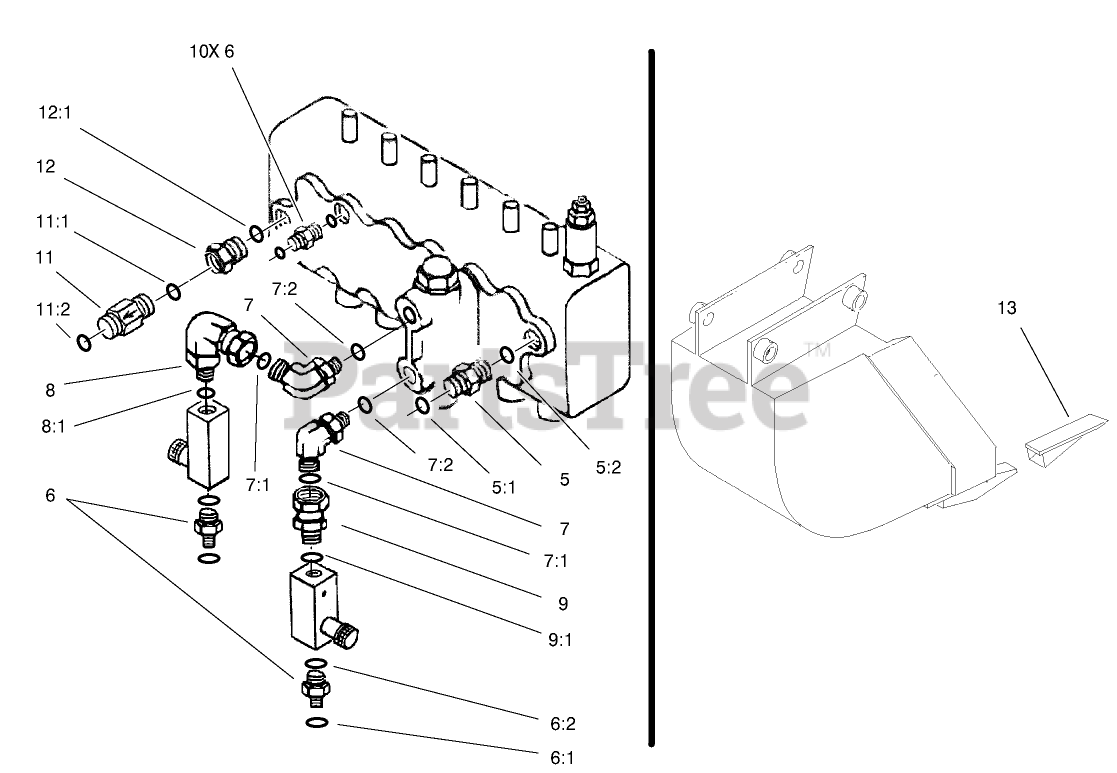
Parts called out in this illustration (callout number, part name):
5	FITTING-STRAIGHT
5:1	O-RING
5:2	O-RING
6	FITTING-STRAIGHT
6:1	O-Ring
6:2	O-RING
7	FITTING-ELBOW, 90 DEG
7:1	O-RING
7:2	O-RING
8	FITTING-SWIVEL, 90 DEG
8:1	O-RING
9	FITTING-SWIVEL, STRAIGHT
9:1	O-RING
11	CHECK VALVE
11:1	O-RING
11:2	O-RING
12	REDUCER-ADAPTER
12:1	O-RING
13	TOOTH-BUCKET
